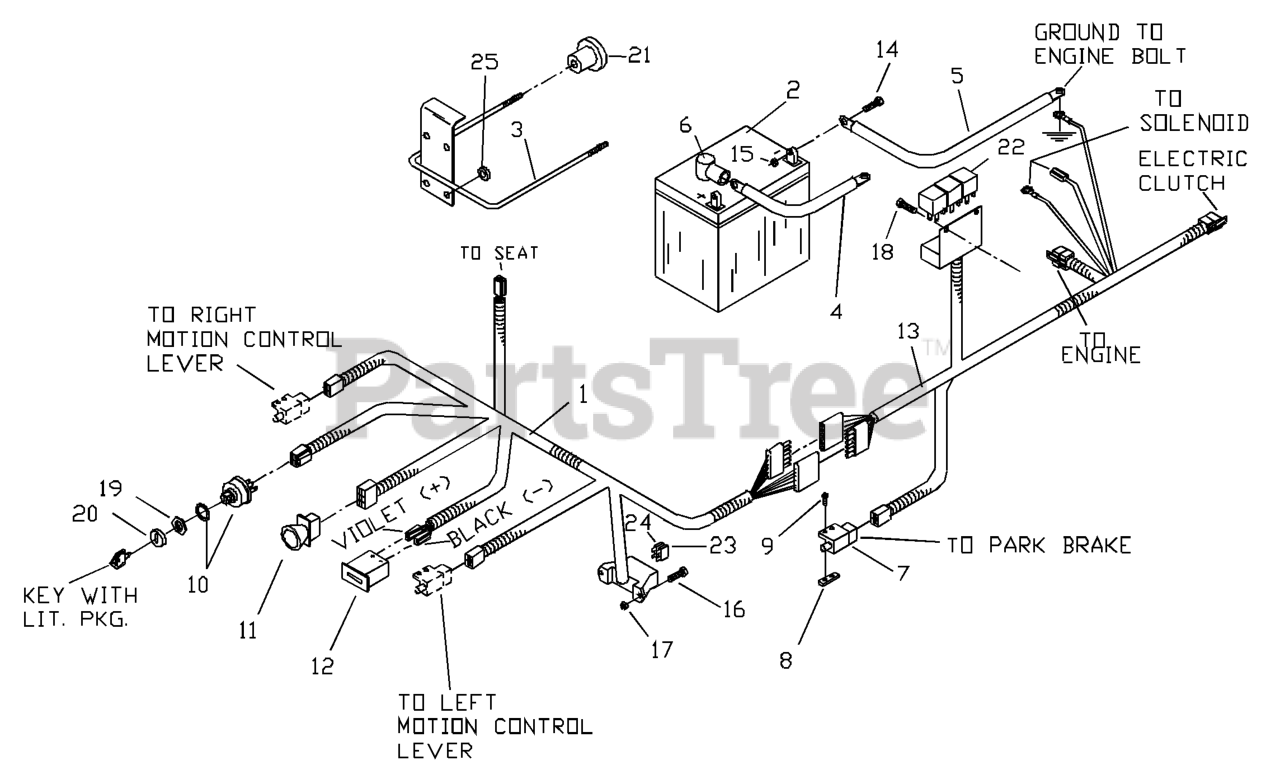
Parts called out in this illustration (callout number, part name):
1	CONSOLE HARNESS
2	BATTERY WET NOT SELLABLE
3	BATTERY HOLD DOWN
4	POST.CABLE LONG
5	CABLE-NEGATIVE
7	SWITCH, INTERLOCK
8	TAPPED PLATE
9	SCREW #10-24 X 5/8
10	IGNITION SWITCH KIT
11	RP.SWITCH, BLADE
12	HOUR METER
13	FRAMES HARNESS
14	HCS 5/16C X 3/4
15	NUT 5/16C CENTERLOCK
16	SCREW, #1--24 X 1/2 SLOTTED
17	NUT 10-24 NYLOC
18	SCREW #10 X 1/2 SELF TAPPING
19	DNO IGNITION NUT
20	CAP IGNITION NUT
23	FUSE, 7.5 AMP 32 VOLT ATO
24	FUSE, 20 AMP 32 VOLT ATO
25	GROMMET, BUMPER
